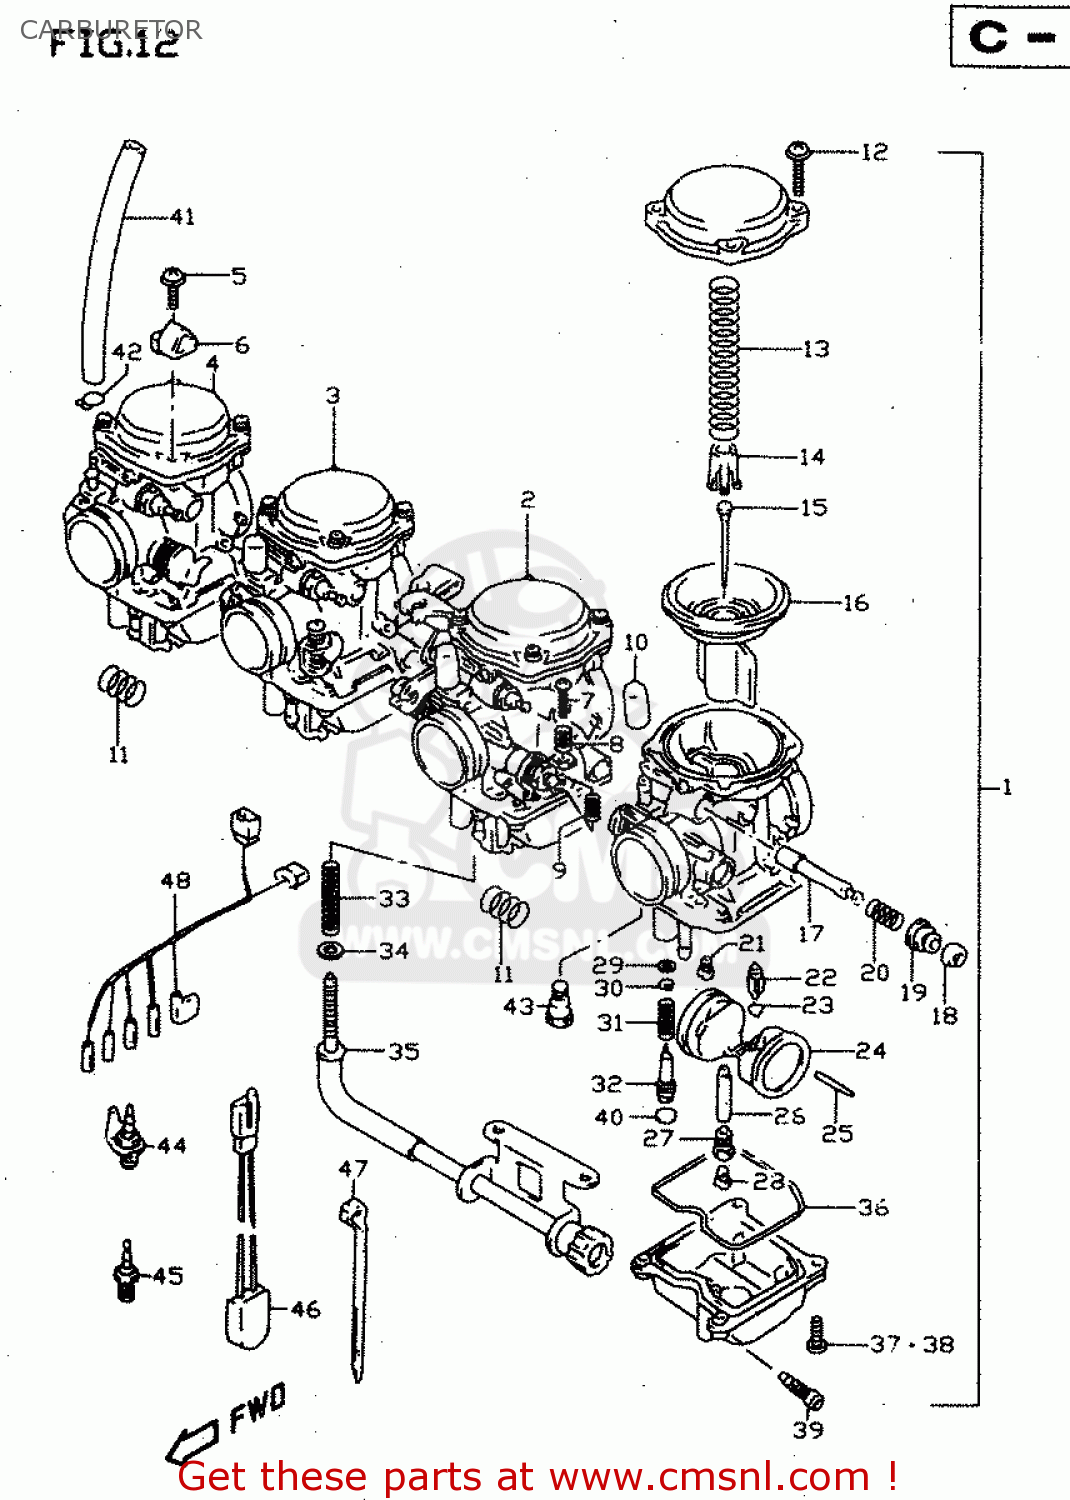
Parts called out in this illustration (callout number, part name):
1	CARBURETOR
2	CARBURETOR
3	CARBURETOR
4	CARBURETOR
5	SCREW
6	STAY,PLATE
7	SCREW
8	SPRING
9	SPRING
10	CAP
11	SPRING
12	SCREW 4X16
13	SPRING
14	SEAT,SPRING
15	NEEDLE,JET
16	PISTON
17	VALVE,STARTER
18	CAP
19	CAP
20	SPRING
21	JET,SLOW(35)
22	VALVE ASSY,NEEDLE
23	CLIP
24	FLOAT ASSY
25	PIN,FLOAT
26	JET,NEEDLE
27	HOLDER,NEEDLE JET
28	JET,MAIN(105)
29	O RING
30	WASHER
31	SPRING
32	SCREW,ADJUST
33	SPRING
34	WASHER
35	ADJUSTER
36	O RING
37	SCREW
38	SCREW
39	PLUG,DRAIN
40	CAP
41	HOSE(5X9X600)
42	CLIP
43	ADAPTER,HEATER
44	HEATER ASSY,CARBURETOR(15W)
45	HEATER, CARB.
46	THERMO SWITCH,CARB HEATER
47	CLAMP(L:165)
48	WIRE,CARB HEATER LEAD
